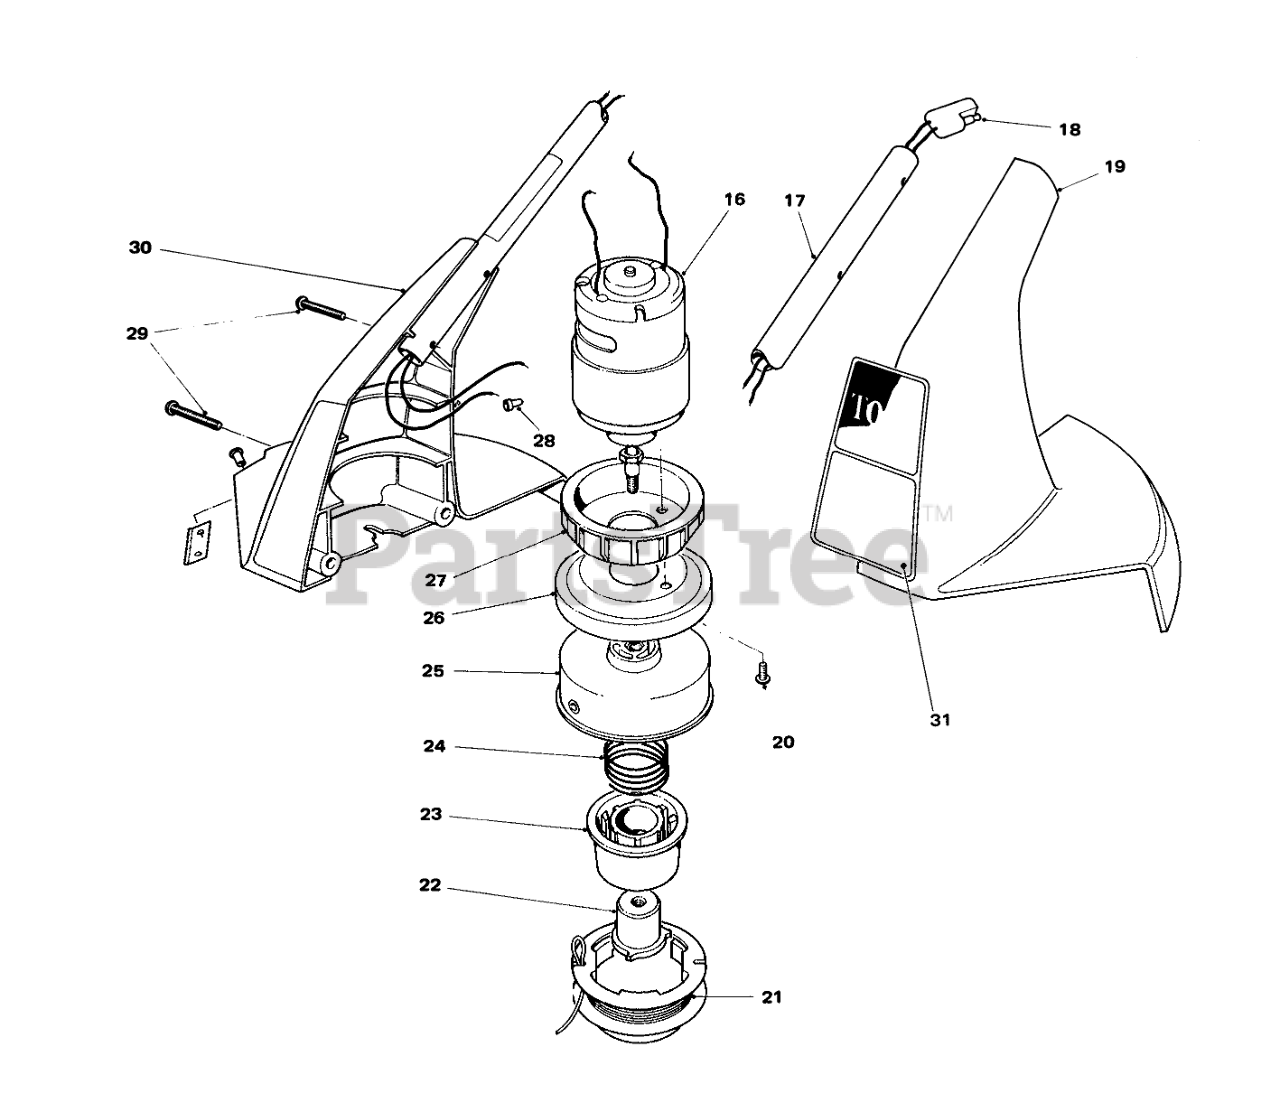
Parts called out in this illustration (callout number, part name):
16	Motor
17	EXTENSION HANDLE
18	WIRING HARNESS LOWER
19	Housing-L.H.
20	SCREW-PPH
21	Prewound Spool
22	DRIVER
23	CORE - SPOOL
24	Spring
25	Drum w/Eyelet
26	DRUM CUP
27	Casting-Heat Sink
28	CONNECTOR WIRE JOINT
29	SCREW-PLASTITE
30	R.H. Motor Housing (Incl. Ref. #17&18)
31	Decal, Cordless
